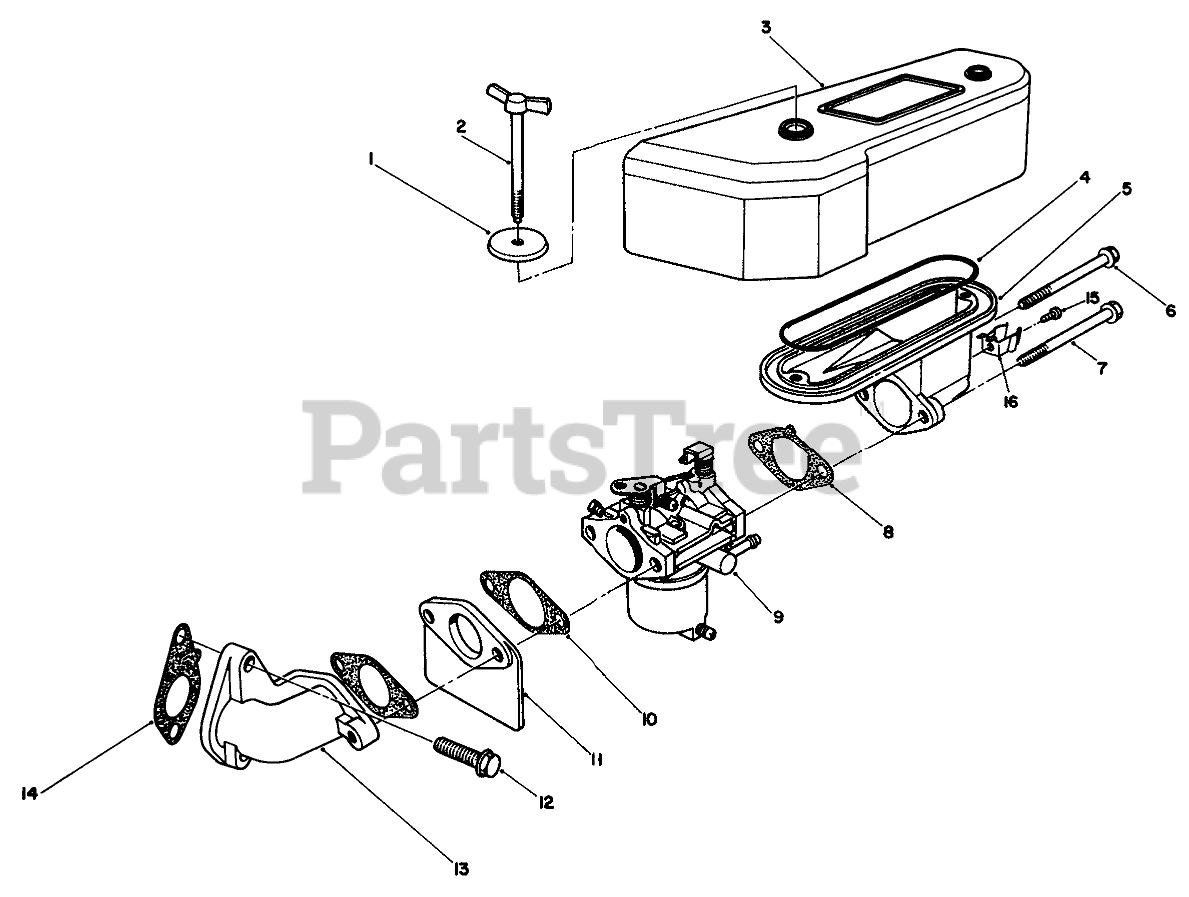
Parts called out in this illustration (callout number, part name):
1	Washer
3	Filter ASM
4	Gasket
5	Pipe-Intake
8	Gasket
9	Carburetor ASM
10	Gasket
11	Insulator
12	Bolt-Flanged (8X25)
13	Pipe-Intake
14	Gasket
15	Screw
